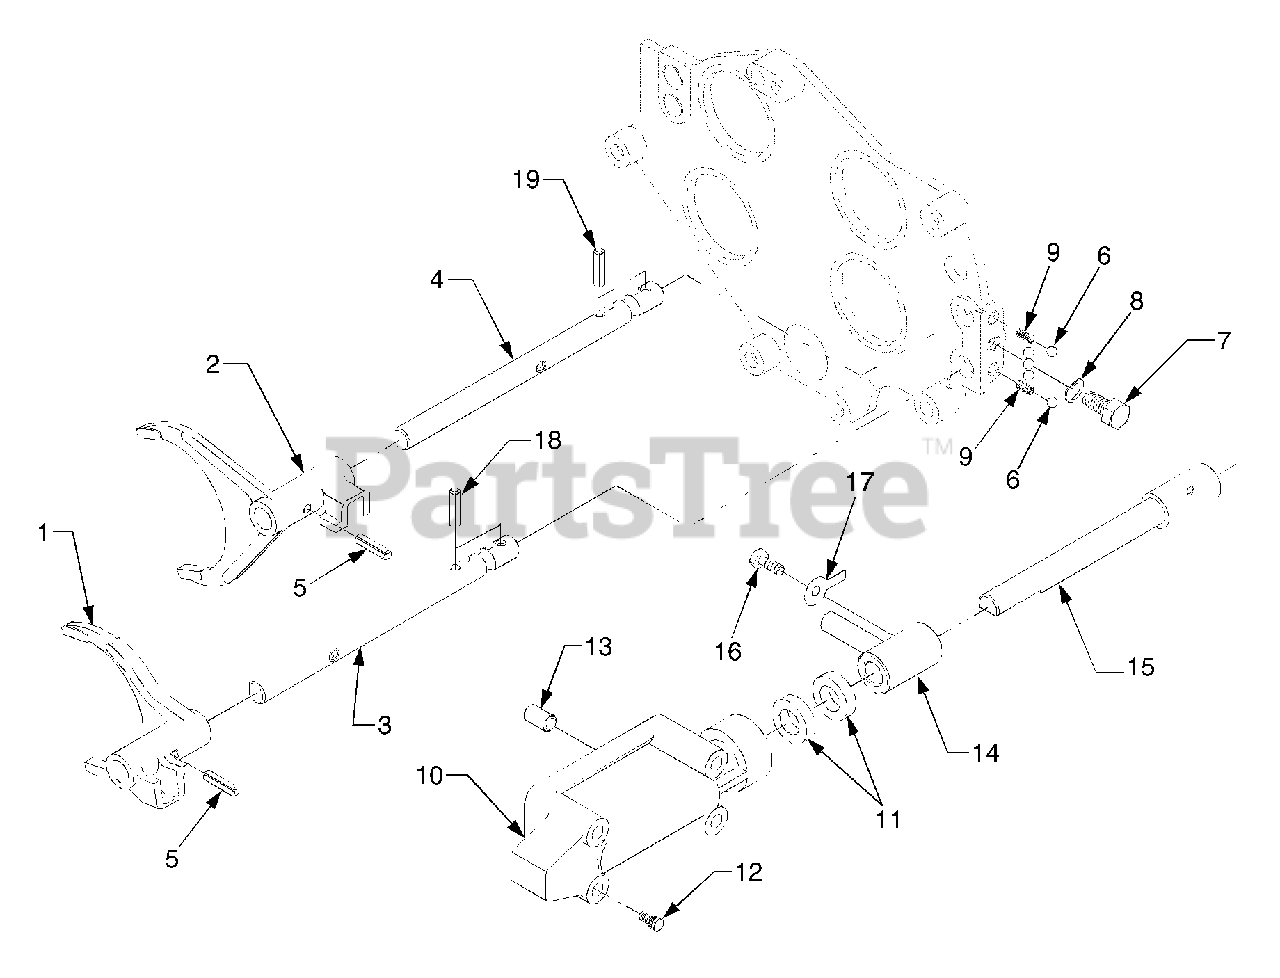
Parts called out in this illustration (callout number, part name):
1	Fork, Shift (1,2)
2	Fork, Shift (3,4)
3	Rod, Fork (1,2)
4	Rod, Fork (3,4)
7	Bolt, Stopper
8	Washer, Spring
10	Cover, Shift (Main)
13	Pin, Straight
